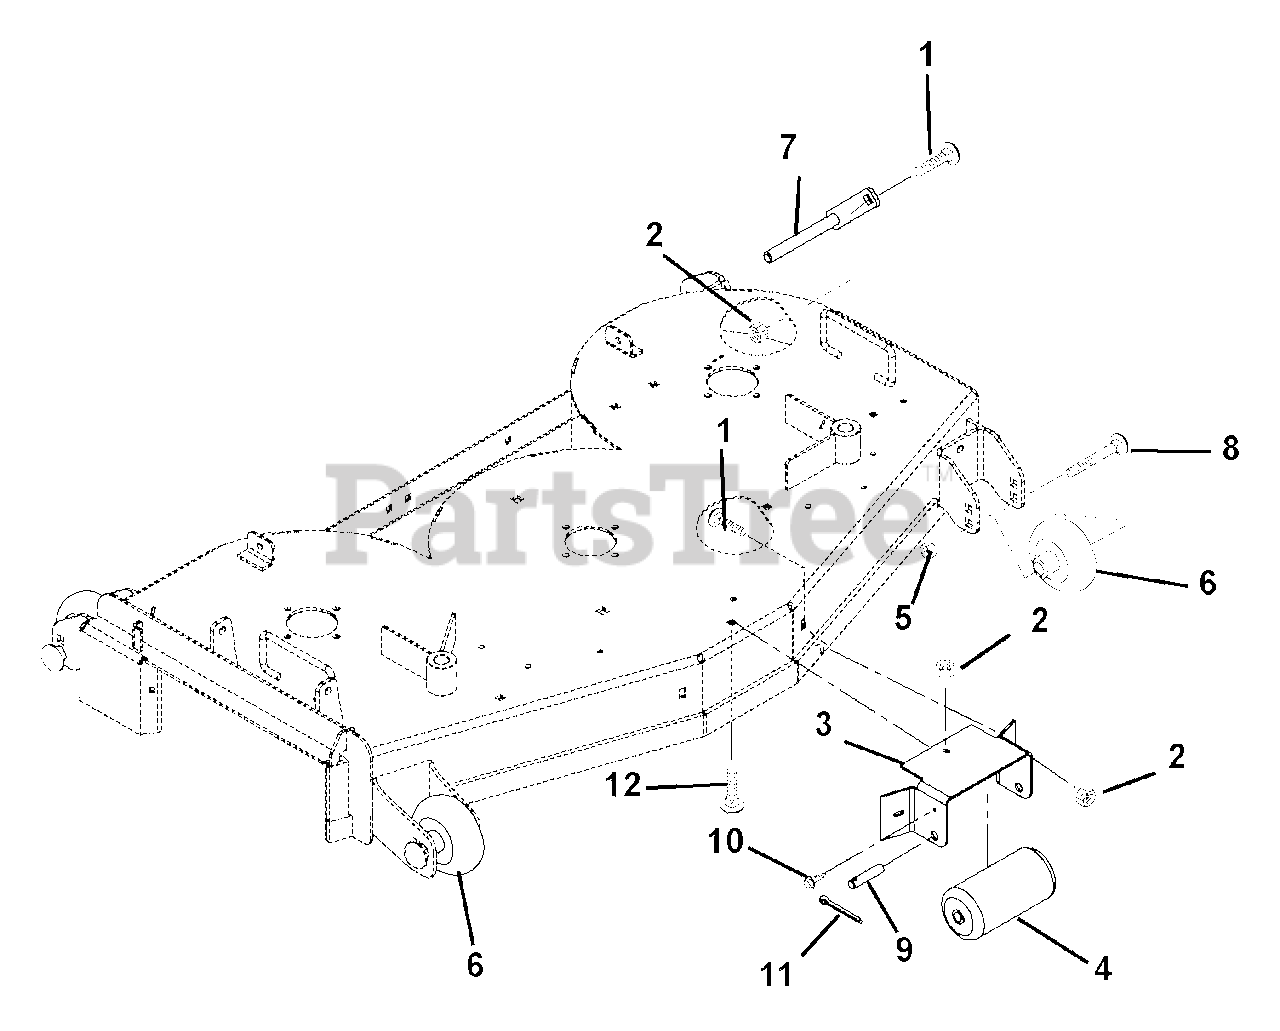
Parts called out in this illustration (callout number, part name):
1	@BLT-RDHDSQNK .38-16X1.00 G5YZ
2	@NUT-LK-TOP-FLG .38-16 YWZC
3	BRACKET - ANTI-SCALP ROLLER
5	@NUT-LK-TOP-FLG .50-13 YWZC
6	WHEEL, 3X5
7	WMT- WHEEL RETAINER
8	BLT-RDHDSQNK .50-13X4.50 G2 YZ
10	@SCR-TAP .25-20X.50 HWH TR YWZ
11	@PIN-CTR .25X2.00 YWZC
12	@BLT-RDHDSQNK .38-16X.75 G5YZ
